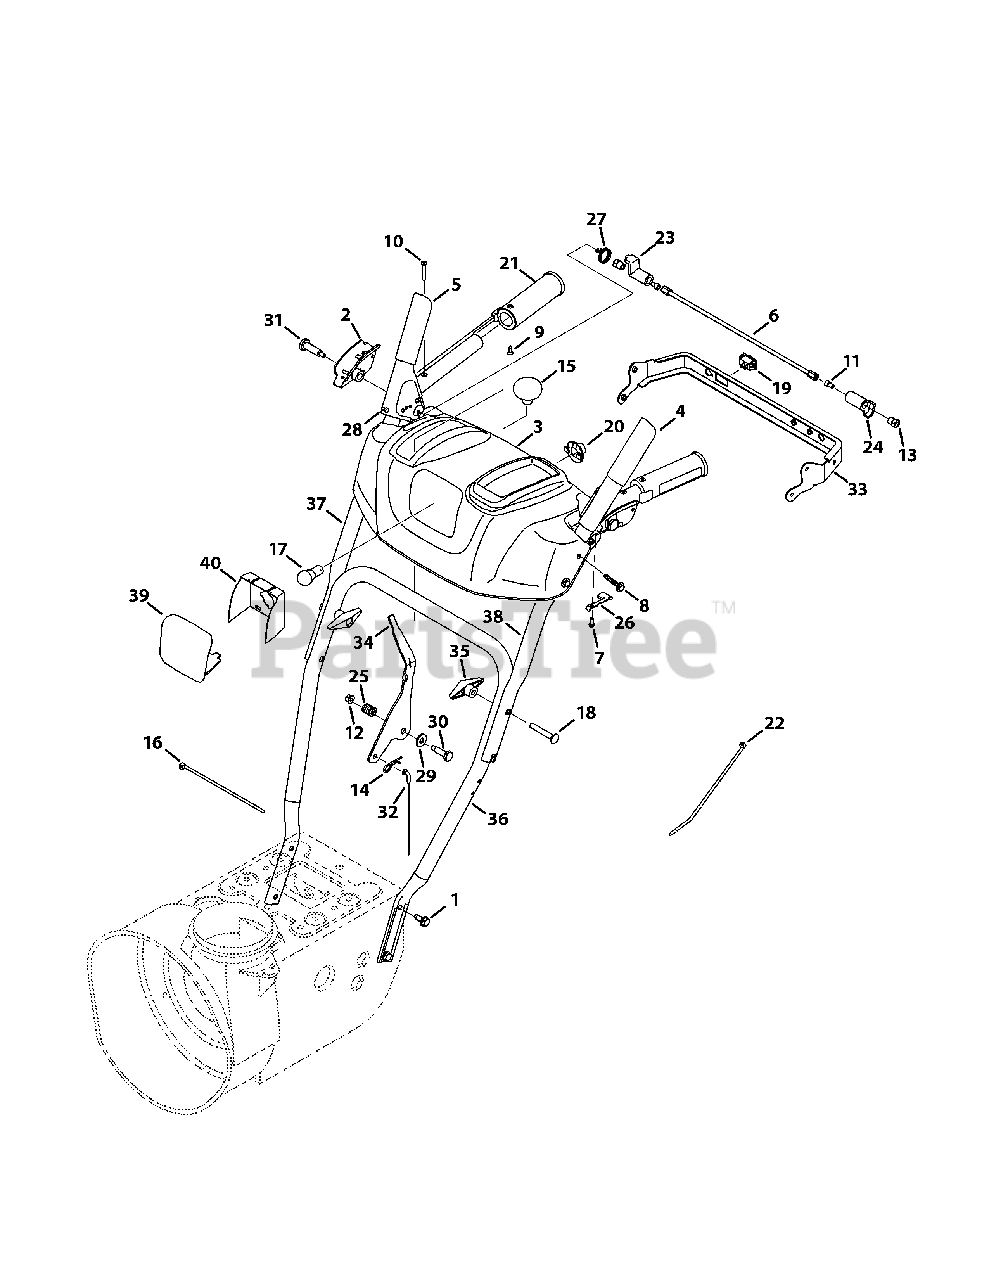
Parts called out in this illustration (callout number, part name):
1	Screw, Taptite, 5/16-18 x .750
2	Clutch Lock, RH
2	Clutch Lock, LH
3	Handle Panel Gray, includes 39 & 40
4	Auger Engage, Black
5	Drive Engage, Black
6	Pivot Rod
7	Screw, Plastite, 8-16 x .50
8	Screw, Taptite, 1/4-20 x 1.625
9	Screw, 10-16 x 0.625
10	Screw, 10-24 x 1.375
11	Screw, 1/4-20 x .50
12	Nut, Flange Lock, 1/4-20
13	Nut, Hex, 1/4-20
14	Click Pin, .092 x 1.64
15	Shift Knob
16	Cable Tie, 7"
17	Lamp, 12.8V, 357cc Engine
18	Screw, Carriage, 5/16-18 x 2.25
19	Heated Grip Switch
20	Lamp Socket
21	Heated Grip
22	Cable Tie, Push Mount
23	Plate, Lock
24	Cam, Clutch Lock
25	Compression Spring, .39 x .60 x .88
26	Clutch Lock Spring
27	Torsion Spring, 0.8156 x .3038
28	Rubber Bumper
29	Washer, Flat, .385 x .87
30	Screw, Shield, .374 x 1.05
31	Screw, Shoulder, .437 x 1.345 x 1/4-20
32	Speed Selector Cable
33	Panel Bracket
34	Shift Lever
35	Wing Knob
36	Lower Handle
37	Upper RH Handle
38	Upper LH Handle
39	Lens Panel
40	Lens Label
